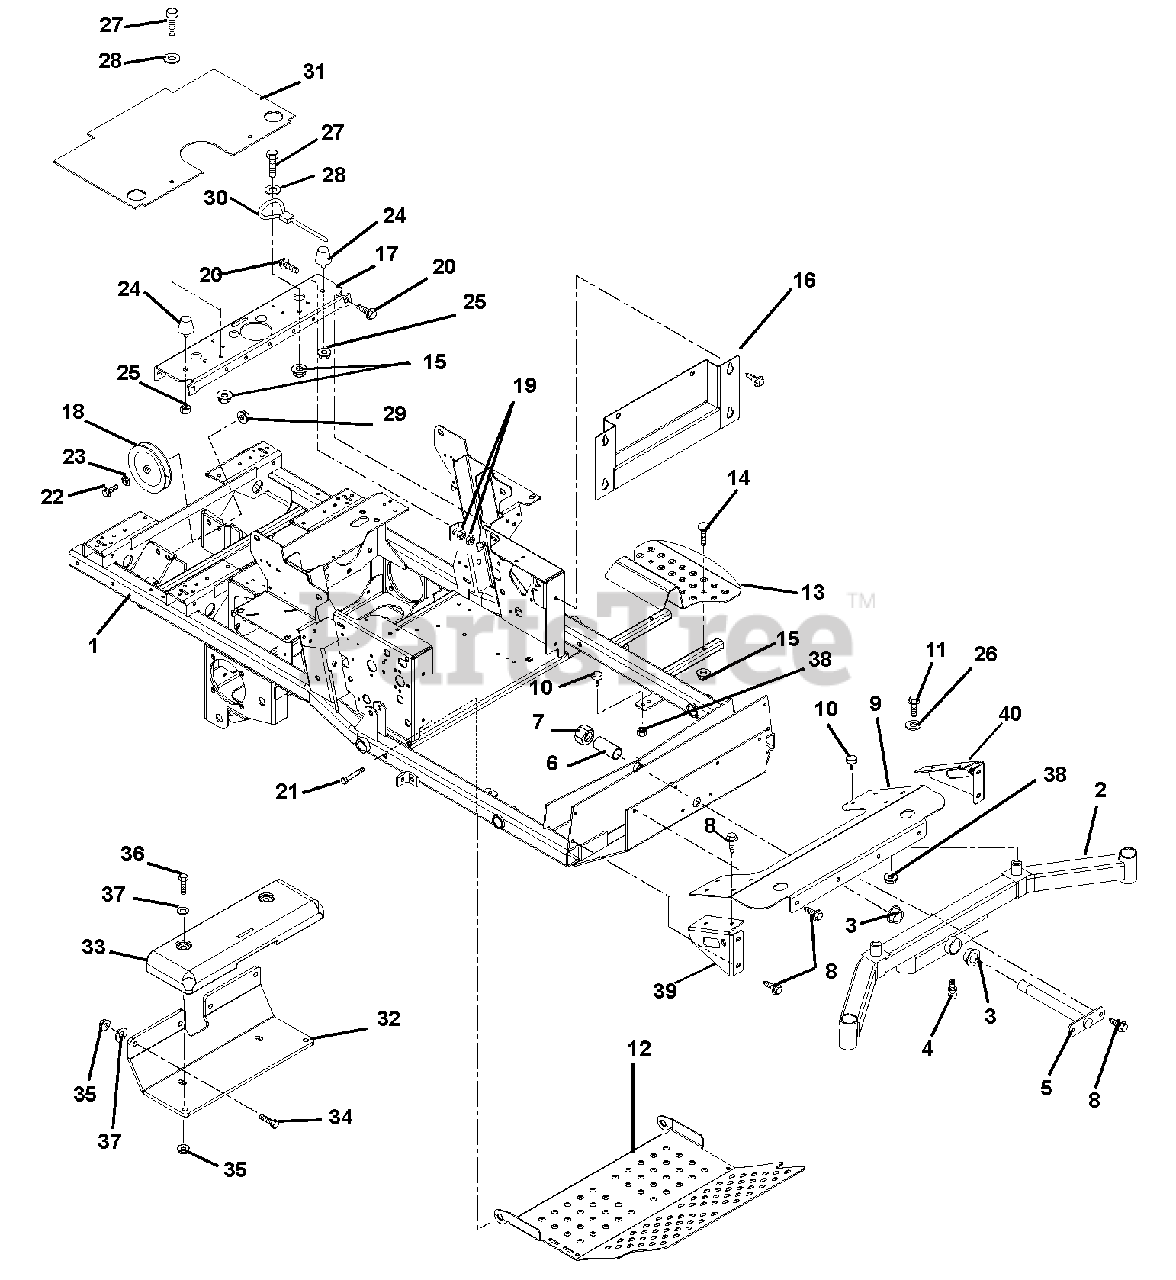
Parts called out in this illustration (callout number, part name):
1	Weldment, Frame
2	Weldment, Front Axle
3	Bushing, Flange 1.020 x 1.385 x .75 x 1.75
4	Fitting, Lube 45 Degree GM411031
5	Pin, Axle
7	Nut, Locking Nylon 1.0-14
8	Screw, Tapping .38-16 x .75
9	Axle Cover
10	Button, Bumper
11	Bolt, Hex .50-20 x 1.00 Grade 5
12	Panel, Inspection
13	Step, Ingress
14	Bolt, Round Head Square Neck .31-18 x 1.75 Grade 5
15	Nut, Locking Top Flange .31-18
16	Plate, Kick
17	Channel, Cross
18	Pulley, Idler
19	Nut, Retainer .375-16 x .37
20	Bolt, Serrated Flange Washer Head .38-16 x 1.00
21	Bolt, Hex .50-13 x 3.25 Grade 5
22	Bolt, Hex .50-13 x 2.25 Grade 5
23	Washer, Flat Steel .505 x .88 x .072
25	Nut, Spin Lock-Flange .312-18
26	Washer, Flat Steel .064 x 1.810 x .250
27	Bolt, Hex .31-18 X 1.00 Grade 5
28	Washer, Flat Steel .344 x 1.125 x .135
29	Nut, Locking Top Flange .50-13
30	Cable, Seat Prop
31	Guard, Grass
32	Bracket, Weight
33	Weight, Cast Iron
34	Bolt-Hex .50-13 x 1.25 Grade 5
35	Nut, Locking Top Flange .50-13
36	Bolt, Hex .50-13 x 4.50 Grade 5
37	Washer, Flat Steel .531 x 1.06 x .095
38	Nut, Spin Lock, Flange .312-18
39	Weldment, Right Hand Axle Cover Support
40	Weldment, Left Hand Axle Cover Support
